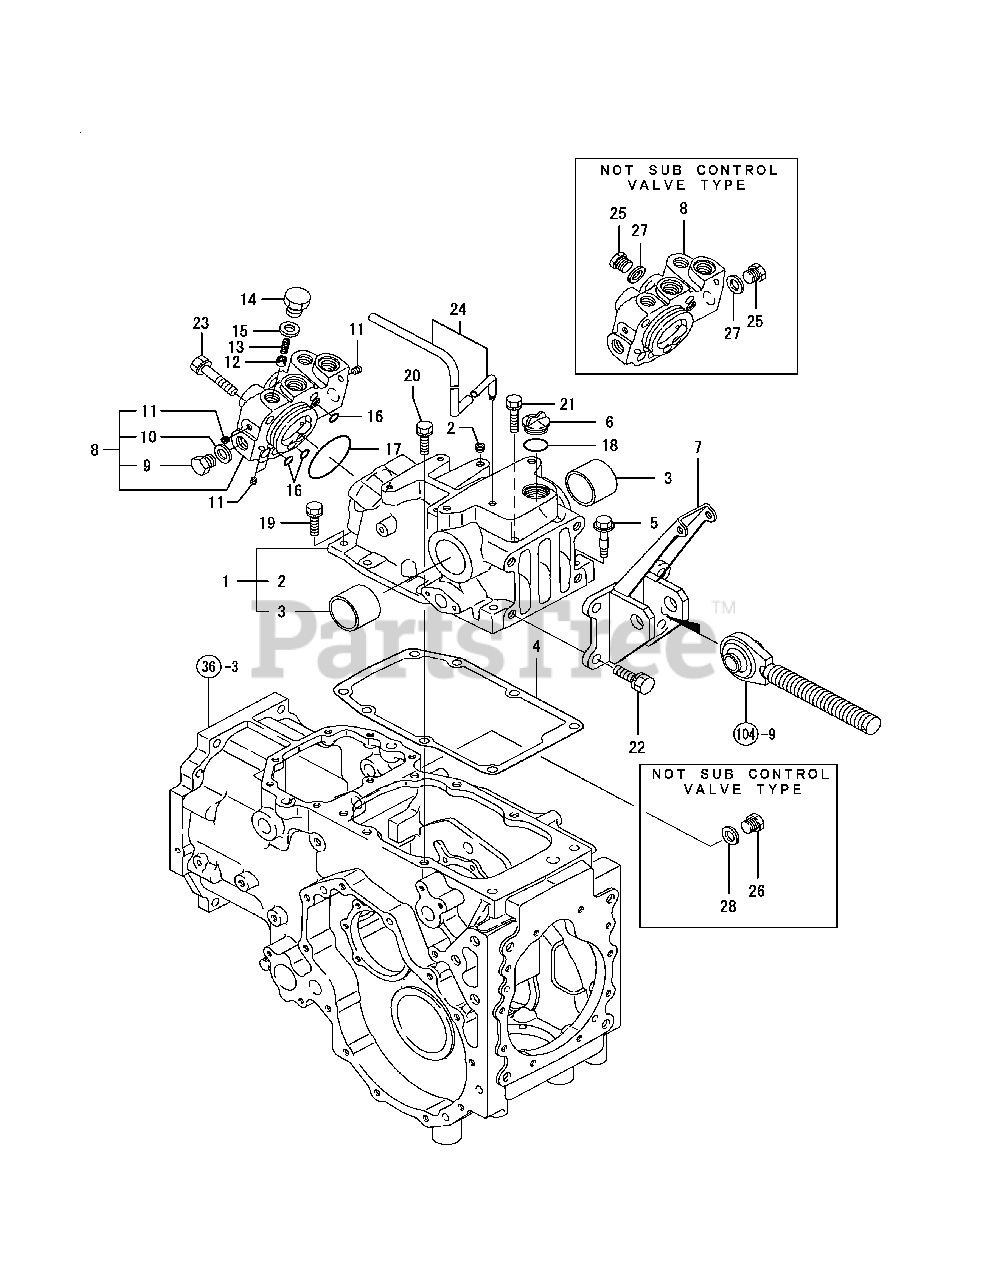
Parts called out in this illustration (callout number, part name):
1	HOUSING, HYDRAULIC
2	PLUG PT1/8,SCREW
5	BOLT 10X50,REAMER
7	TOP LINK HINGE
8	HEAD, CYLINDER ASSY
9	PLUG 3/4-16UNF
11	PLUG PT1/8,SCREW
16	O-RING 1B P-11.0
17	O-RING 1B G-60.0
18	O-RING 1A 2030
19	BOLT M10X 30
22	BOLT W/WASHER M12X30
25	PLUG 3/4-16UNF (NOT FOR SUB CONTROL VALVE TYPE)
26	PLUG 3/4-16UNF (NOT FOR SUB CONTROL VALVE TYPE)
27	PACKING -19 (NOT FOR SUB CONTROL VALVE TYPE)
28	PACKING -19 (NOT FOR SUB CONTROL VALVE TYPE)
